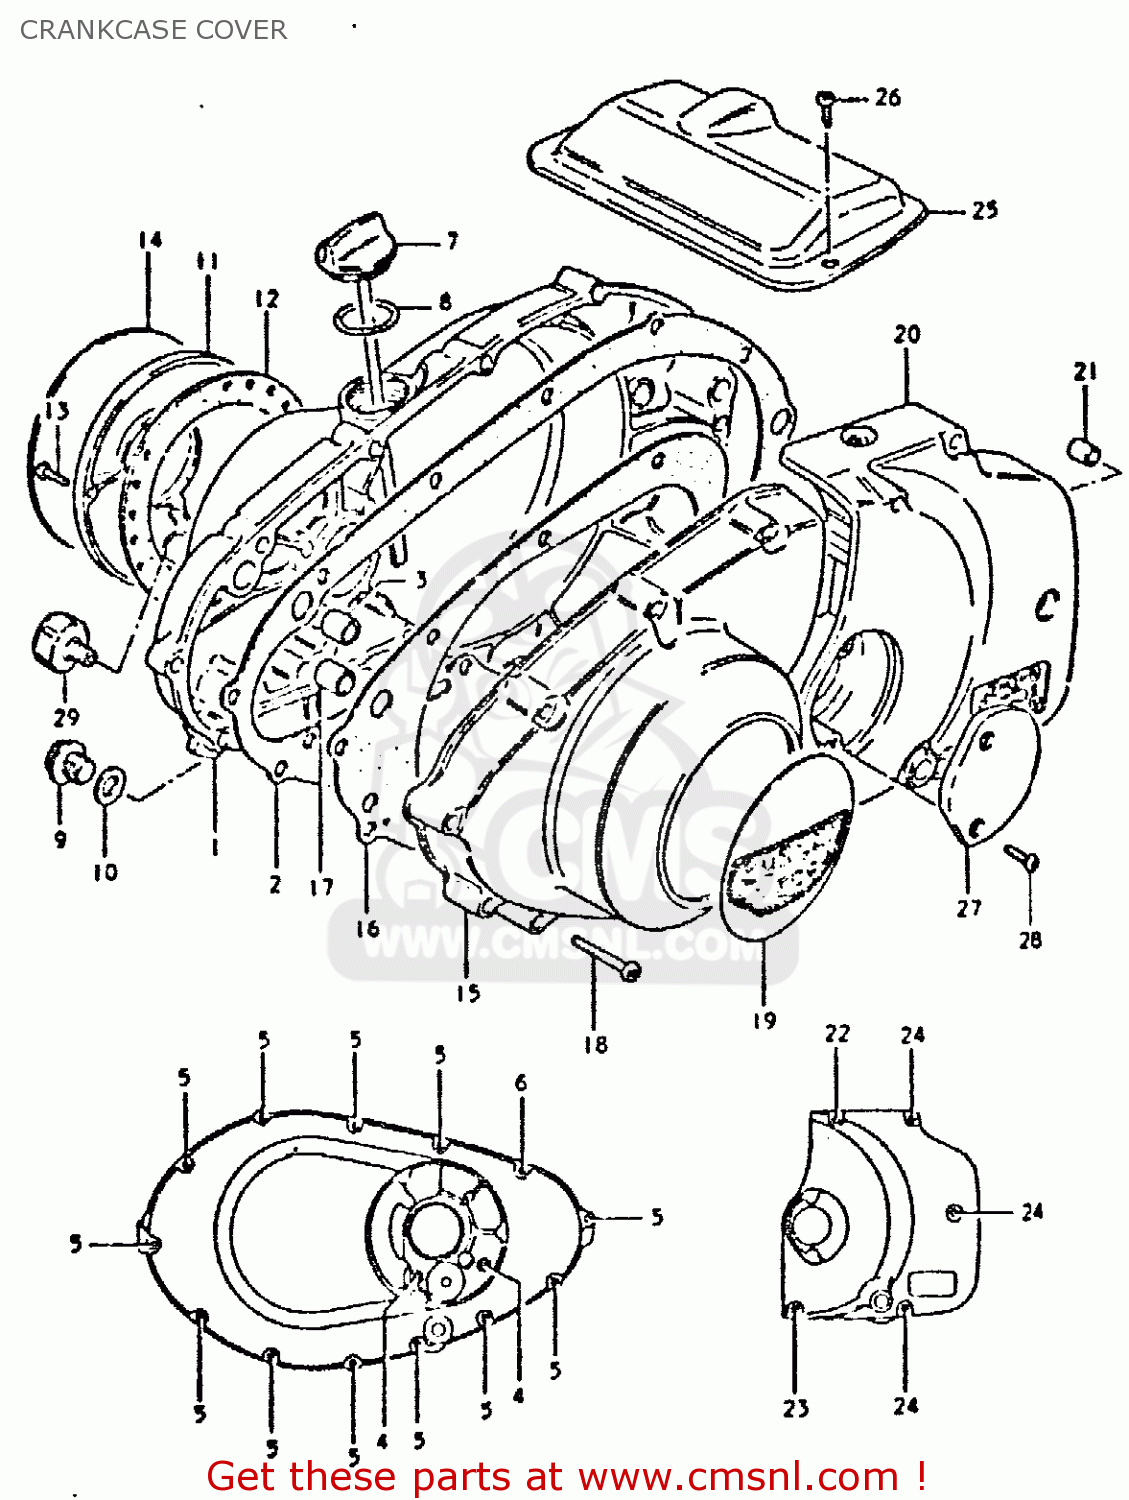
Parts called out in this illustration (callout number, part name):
1	COVER,CLUTCH
2	GASKET,CLUTCH COVER (MCA)
3	PIN
4	SCREW
5	SCREW (6X35)
6	SCREW
7	GAUGE,OIL LEVEL
8	O-RING
9	PLUG (14X12)
10	GASKET(14X19.2X2) (NAS)
11	COVER,CONTACT BREAKER
12	GASKET,CONTACT BREAKER COVER (NAS)
13	SCREW
14	EMBLEM
15	COVER
16	GASKET,MAGNETO COVER (MCA)
17	PIN
18	SCREW (6X35)
19	EMBLEM
20	COVER,SPROCKET
21	PIN
22	SCREW 6X65
23	SCREW
24	SCREW
25	COVER,STARTER MOTOR
26	SCREW
27	CAP,CLUTCH RELEASE ADJUST
28	SCREW 5X12
29	SWITCH ASSEMBLY
